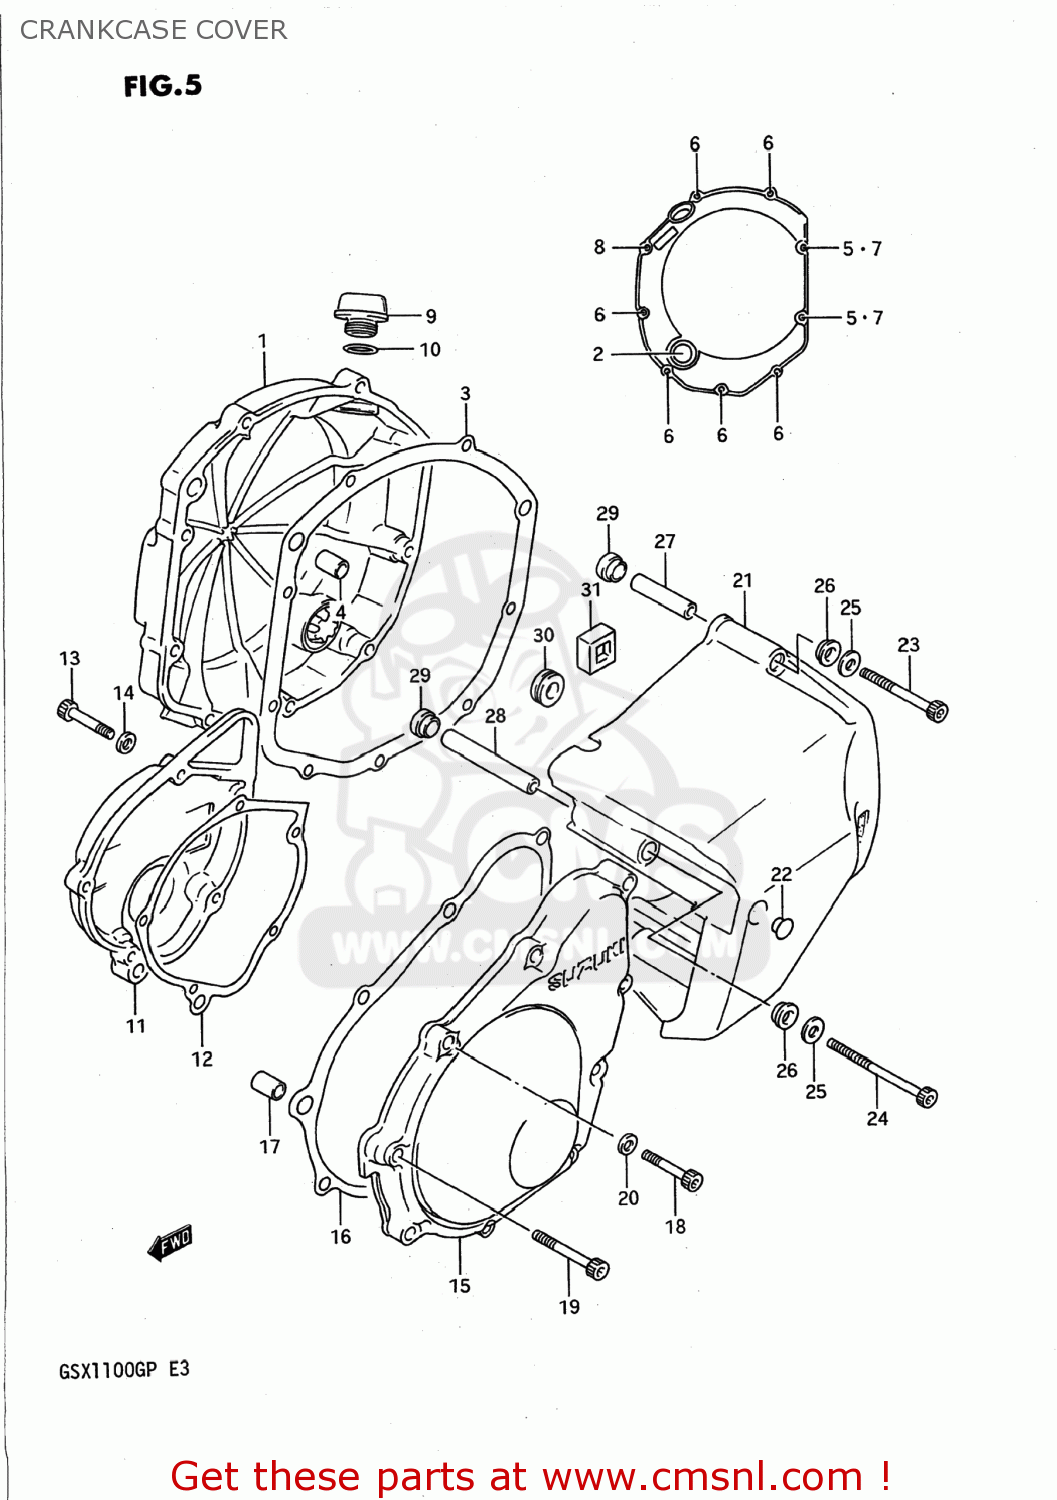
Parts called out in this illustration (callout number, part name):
1	COVER COMP,CLUTCH
2	LENS,OIL LEVEL CHECK
3	GASKET,CLUTCH COVER (NAS)
4	PIN
5	GASKET(5.8X11X1.2) (NAS)
6	BOLT
7	BOLT
8	BOLT
9	PLUG (20X10)
10	O RING(D:3.1,ID:16.8)
11	COVER,SIGNAL GENERATOR
12	GASKET,SIGNAL GENERATOR COVER (NAS)
13	BOLT
14	GASKET(5.8X11X1.2) (NAS)
15	COVER,STARTER GEAR
16	GASKET,STARTER GEAR COVER (NAS)
17	PIN (11X20)(SUS)
18	BOLT
19	BOLT
20	GASKET(5.8X11X1.2) (NAS)
21	COVER,SPROCKET
22	CAP(OD:12)
23	BOLT
24	BOLT
25	WASHER
26	WASHER(8.7X15X2.1)
27	SPACER (L=45.9)
28	SPACER(6.1X9X55.9)
29	WASHER(8.7X16X5)
30	CUSHION
31	DAMPER,SECONDARY COVER
